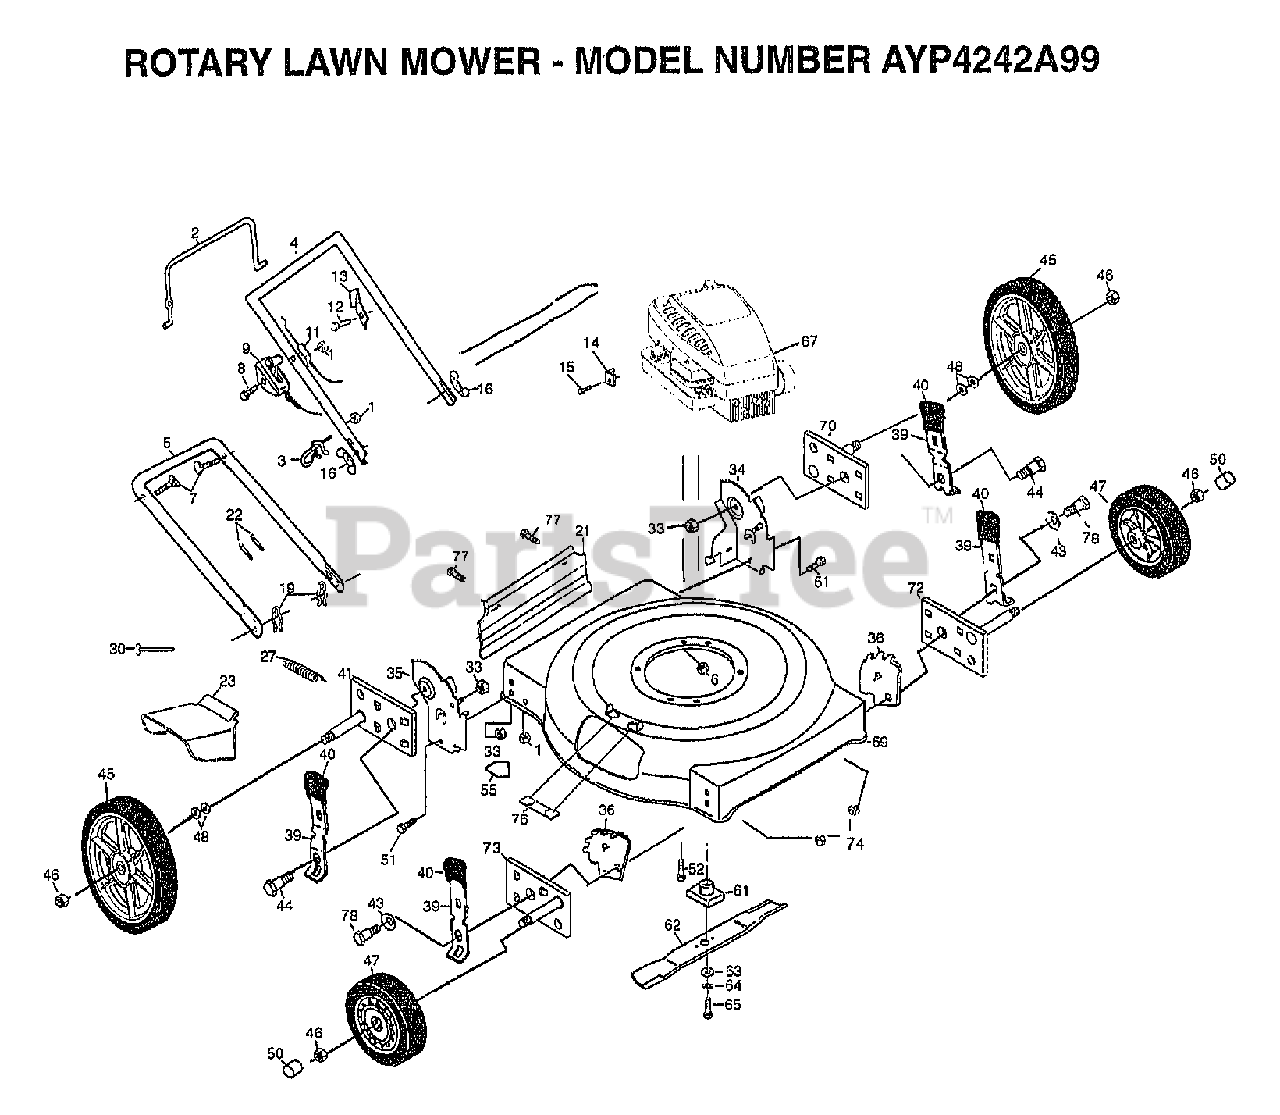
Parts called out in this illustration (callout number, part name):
2	CONTROL BAR PM
3	ROPE GUIDE
5	LOWER HANDLE
7	BOLT.HANDLE.LM
8	SCREW.HXHD.WASH.
9	"CONTROL, THROTTLE"
11	"CABLE.MZR.47"""
12	TAPPING SCREW
13	"BRKT,UPSTOP"
14	CABLE CLAMP
15	SCREW PM
16	"NUT,WING PM"
19	HAIRPIN COTTER
21	SKIRT.REAR.FGD.22
23	GUARD.DISCHARGE
27	HINGE.SPRING
30	HINGE.ROD.22SD
34	BRKT.WHEEL.SUPPORT.LEFT
36	WHEEL.BRKT.ADJ.
39	SPRING.SELECTOR.5/9POS
40	KNOB PM
41	AXLE ARM ASSY LR
43	WASHER.BELLEVELLE
44	SHOULDER.BOLT
45	WHL & TIRE
46	HEX FLANGE LOCKNT
48	WAVE WASHER
50	HUB CAP-PLASTIC
51	BOLT
52	BOLT.ENG.3/8-16
55	DECAL-DANGER PM
59	KIT.HSG.22SD.PUSH.RED
61	ADAPTOR.BLADE.LM
62	"BLADE.MULCH.22"""
63	"WASHER,HARDEN"
64	LOCKWASHER
65	SCREW
70	ARM.ASM.AXLE.REAR
72	ARM.ASM.AXLE.RR/LF.
73	ARM.ASM.AXLE.LR/RF
74	LOCKNUT
76	CLIP.CLOSECUT.22SD
77	BOLT LT
78	SHOULDER BOLT
